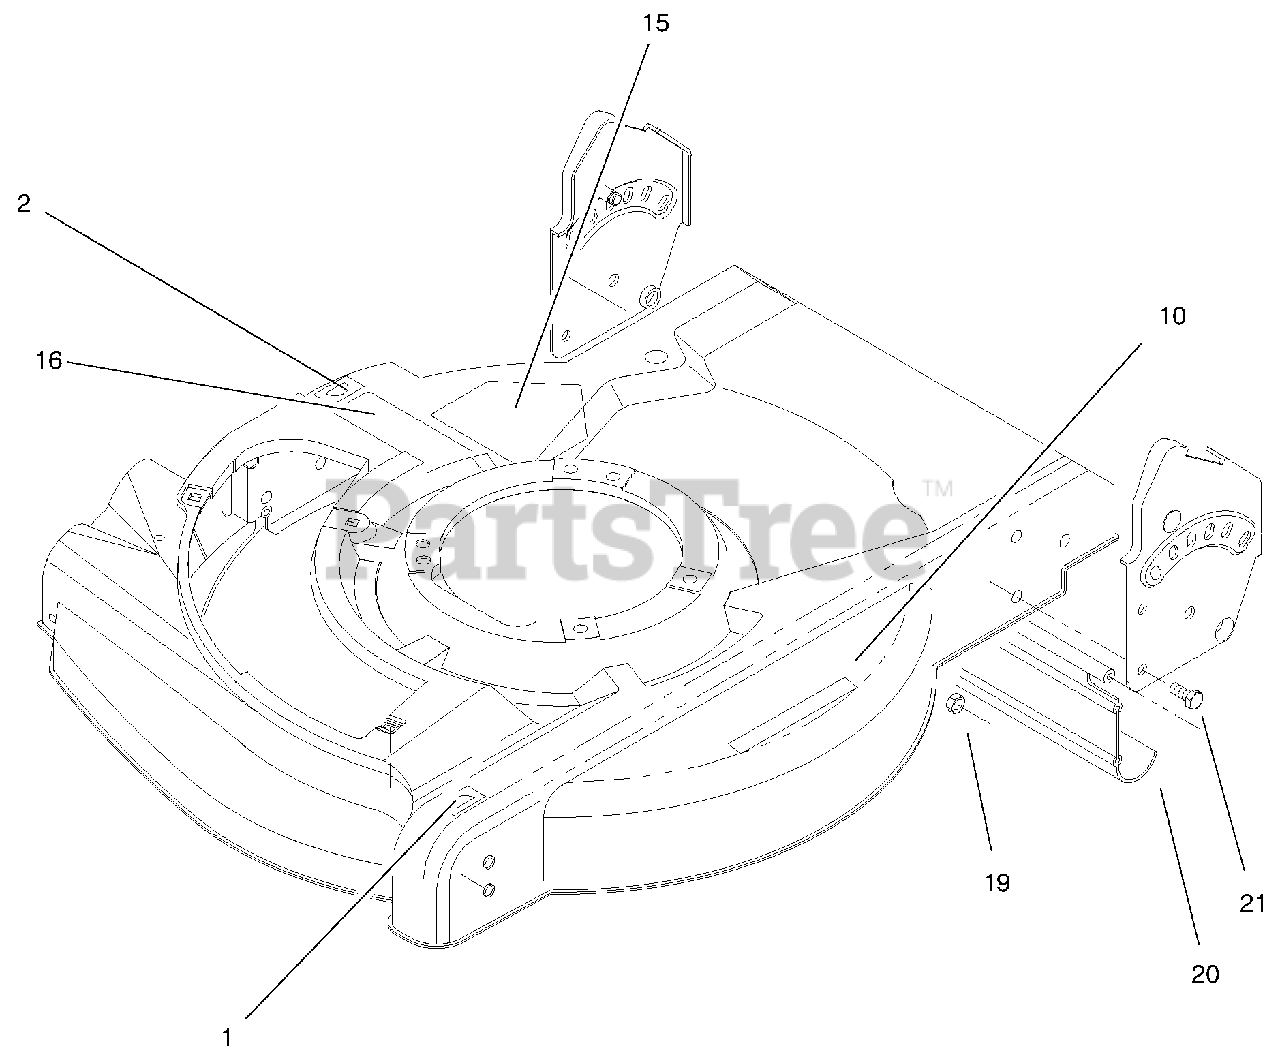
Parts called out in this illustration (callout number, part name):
1	Decal-HOC
2	Decal-HOC
10	Decal-Warning
15	Decal-Danger
16	Decal-Discharge
19	Nut-Lock
20	Shield-Trailing
21	Screw-HH
